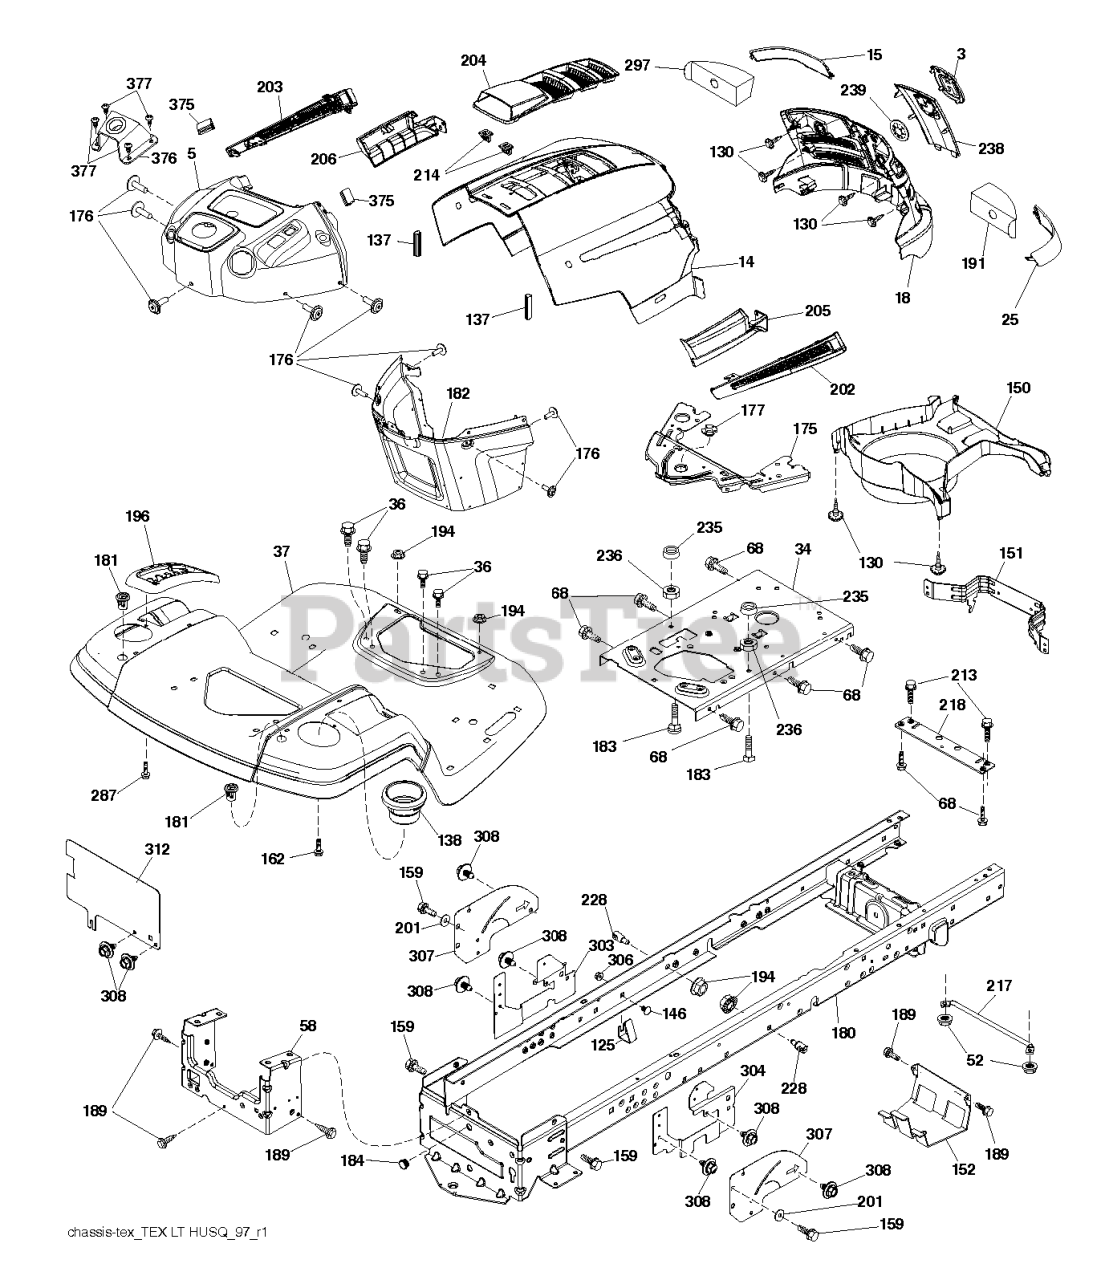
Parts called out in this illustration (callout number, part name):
3	LOGO.HUSQ.GT.LT.CROWN.H
5	DASH.UPPER.HUS.LT.CABLE.CLUTCH
14	HOOD.HUSQVARNA.LT.ORANGE
15	LENS.HUSQVARNA LT.RH
18	GRILLE.SVC.HUSQVARNA.GREY
25	LENS.HUSQVARNA LT.RH
34	PLATE.ENGINE.WELDED.CHASSIS
36	SCREW 5/16"
37	FENDER.TLT.FS.W/CUPHLD.ORANGE
58	DRAWBAR UPPER 2PC SMALL FENDER
125	CLIP.FUEL.LINE
137	BUMPER DASH
138	HOLDER.CUP.LT.GREY
146	BOLT.RDHD.SHT.SQNK.3/8-16X5/8
151	BRACKET PIVOT
152	SHIELD.BROWNING.W/TEX
159	SCREW, 3/8-16X3/4
175	CROSSMEMBER
176	SCREW.#10-24X5/8.RN.QU
177	BUSHING STEERING
180	CHASS.WLDMNT.TL.12GA/2P.48/54
181	BUSHING.MNT.FEND.CRGO.TEX.49
182	DASH.LOWER.PREDATOR LT
184	PLUG.DEMO.625
189	SCREW
191	INSERT.REFLECTIVE.RH.
196	DECKLFT.CONSOL FULL ASSM GREY
201	WASHER
202	VENT.SIDE.HUSQVARNA.LT.RT
203	VENT.SIDE.HUSQVARNA.LT.LFT
204	SUBASM.TOP.VENT.HUSQ.LT
205	SKIRT.SIDE.HUSQVARNA.LT.RT
206	SKIRT.SIDE.HUSQVARNA.LT.LEFT
213	SCREW HEXAGON HEAD SCREW 5/16-
214	CLIP.RETAINER.TINNER.
217	ROD.PIVOT.HOOD
218	X-PIECE.HOOD.STOP.NON/
228	STUD.FASTNER.W/ANTI-ROTATE
236	NUT.CENTERLOCK.5/16-
238	TRIM.HUSQ LT.668
287	SCREW 1/4X20
297	INSERT REFLECTIVE
303	SHIELD.LWR.LH.LTGT.NON30
304	SHIELD.LWR.RH.LTGT.NON30.NOTCH
306	NUT LOCK FLG 3/8-16 UNC
307	SHIELD.UPPER.LT.GT.ISO
308	BOLT.5/16-18UNCX3/4 W/SEMS.BLK
312	COVER DRBAR.LT.FRTTANK.ISO X43
375	BUMPER CLIP-ON. DASH 1"
376	MOUNT.ASM.HUSLT.UPPER.STRNG
377	SCREW 10 X 1/2 ZN PL PHIL PAN
